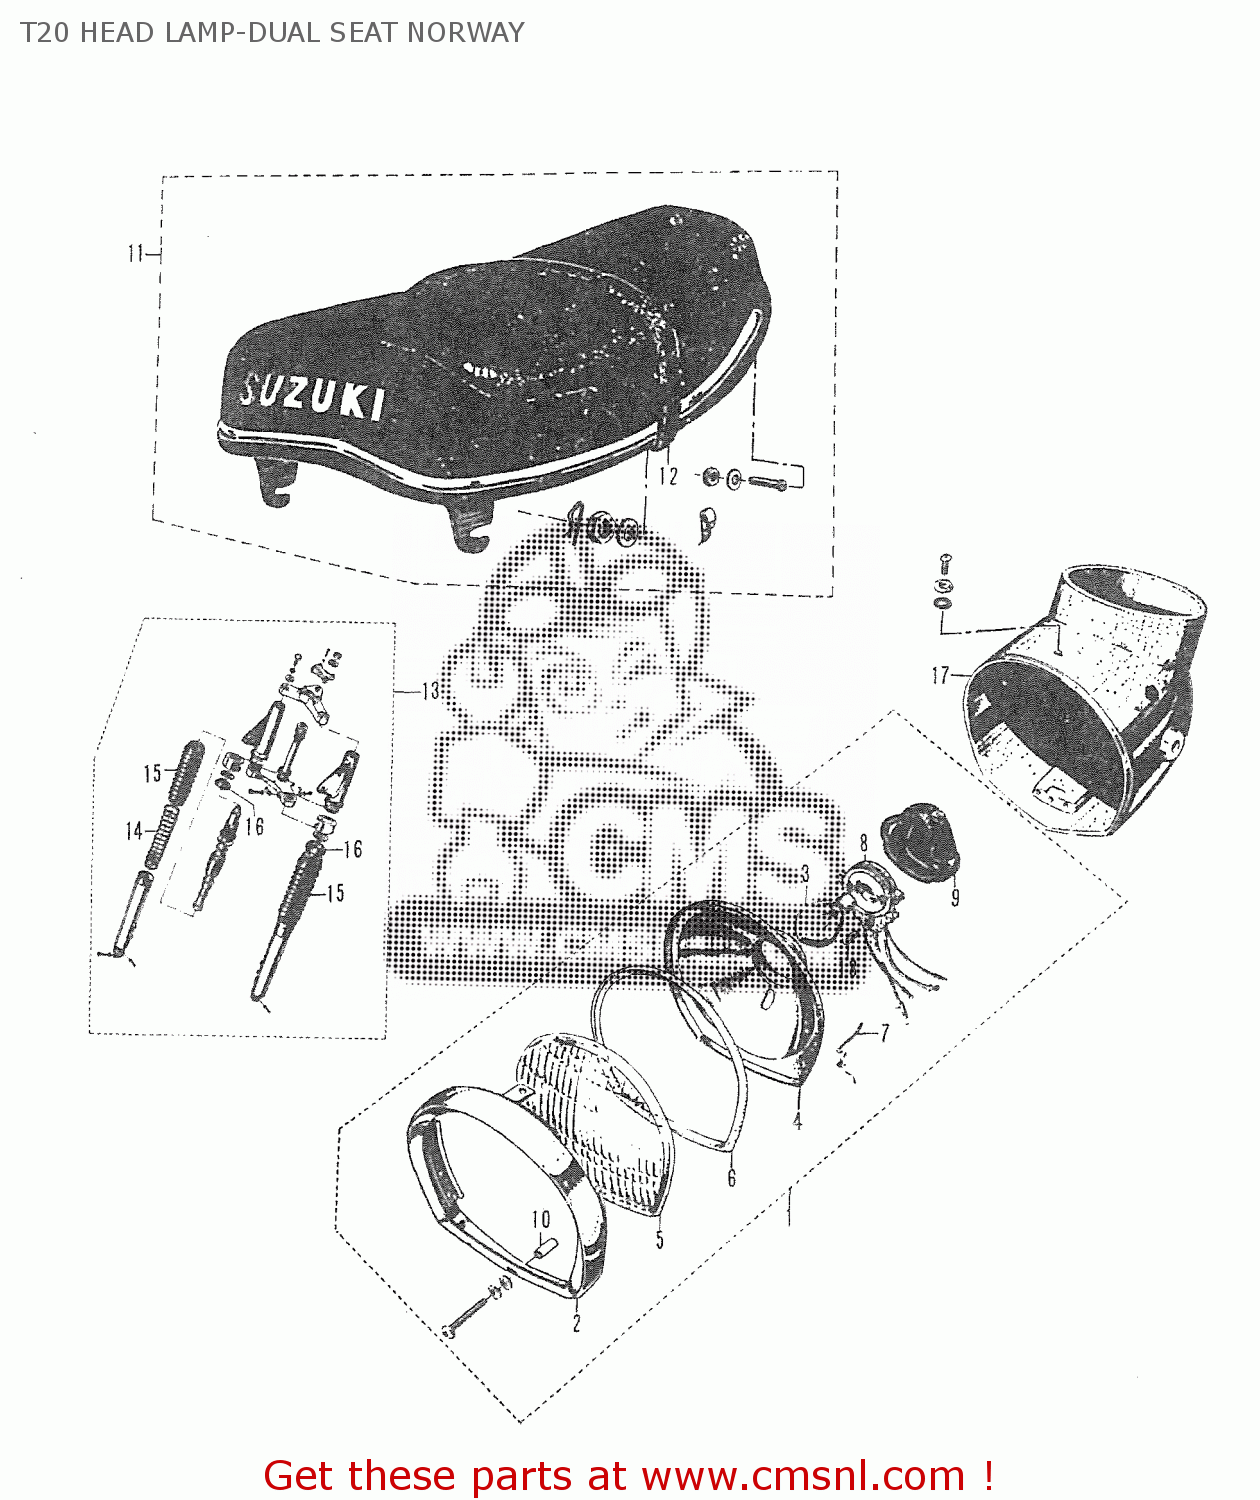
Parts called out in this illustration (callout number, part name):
1	HEAD LAMP ASS'Y
2	HEAD LAMP RIM
3	HEAD LAMP BULB
4	HEAD LAMP REFLECTOR
5	HEAD LAMP LENS
6	HEAD LAMP LENS GASKET
7	SPRING,HEAD LA
8	HEAD LAMP BULB SOCKET
9	HEAD LAMP SOCKET RUBBER CAP
10	HEAD LAMP RIM FITTING SPACER
11	DUAL SEAT ASS'Y
12	DUAL SEAT PASSENGER STRAP
13	FRONT FORK ASS'Y
14	SPRING,FRONT FORK
15	BOOT,SPRING COVER
16	BAND,FRONT FORK COVER
17	HEAD LAMP HOUSING
18	BULB(12V3.4W,STANLEY,A72A)
